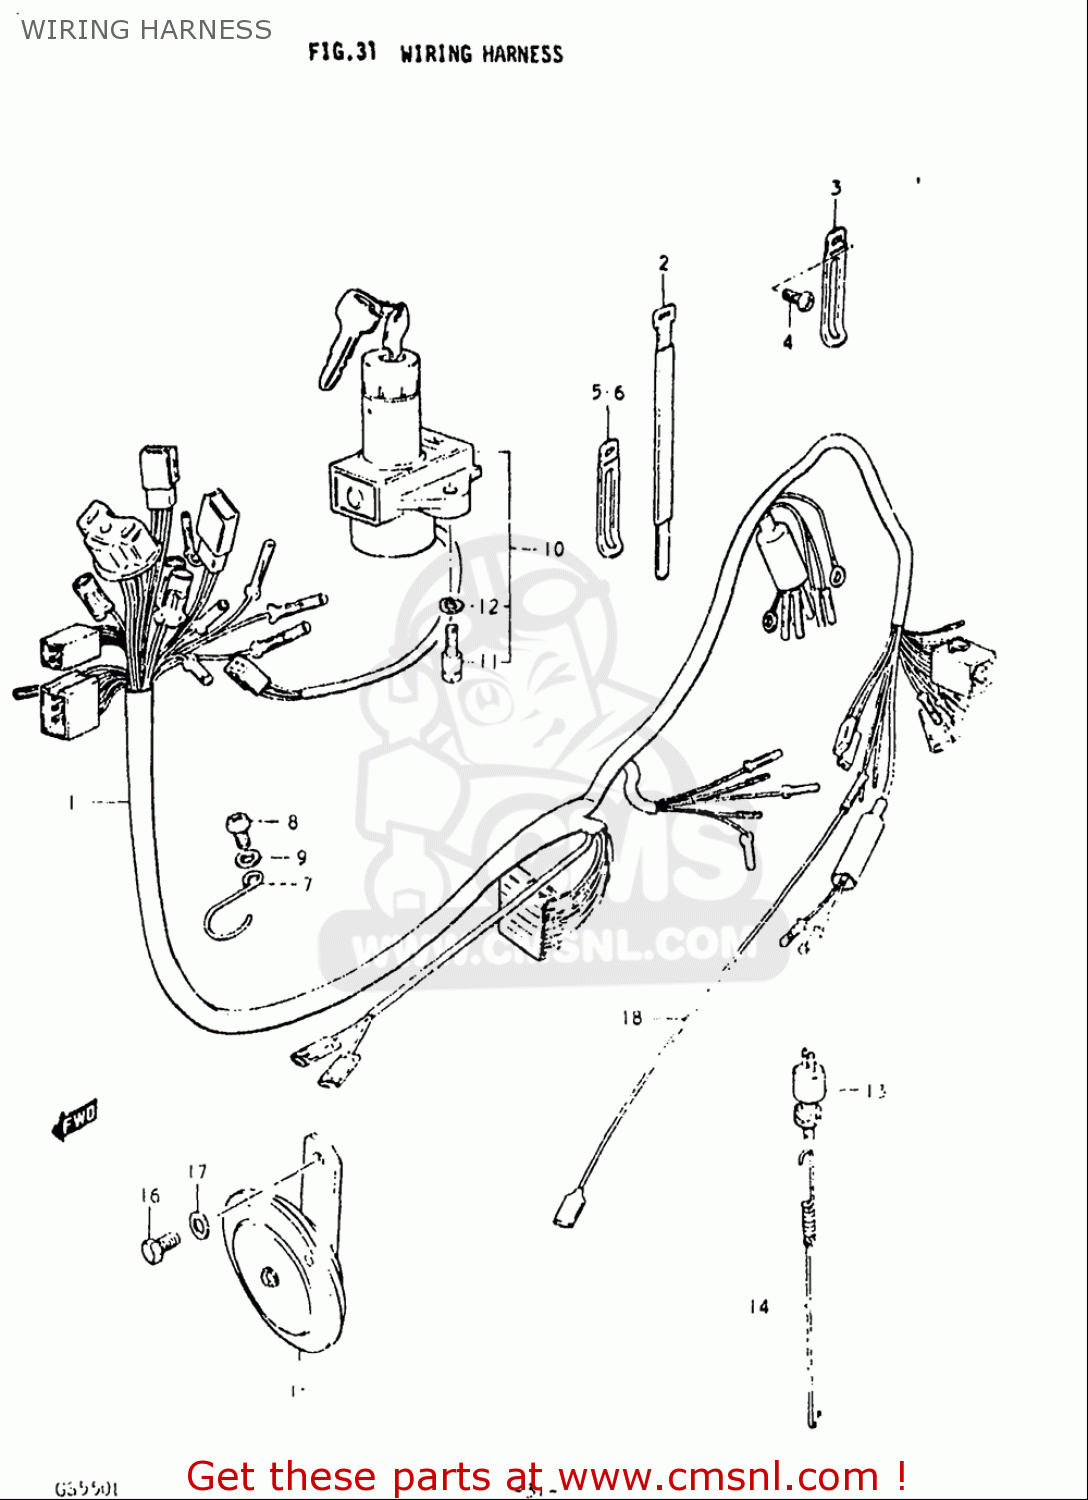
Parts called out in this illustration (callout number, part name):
2	CLAMP
3	CLAMP(L:80 T:1.0)
4	SCREW
5	CLAMP(L:80 T:1.0)
6	CLAMP(L:65)
7	CLIP,WIRING HARNESS
8	SCREW
9	WASHER
10	SWITCH ASSY,IGNITION
11	BOLT
12	WASHER,LOCK
13	SWITCH ASSY,BRAKE LAMP
14	SPRING
15	HORN ASSY
16	BOLT
17	WASHER
18	WIRE,OIL PRESSURE SWITCH LEAD
